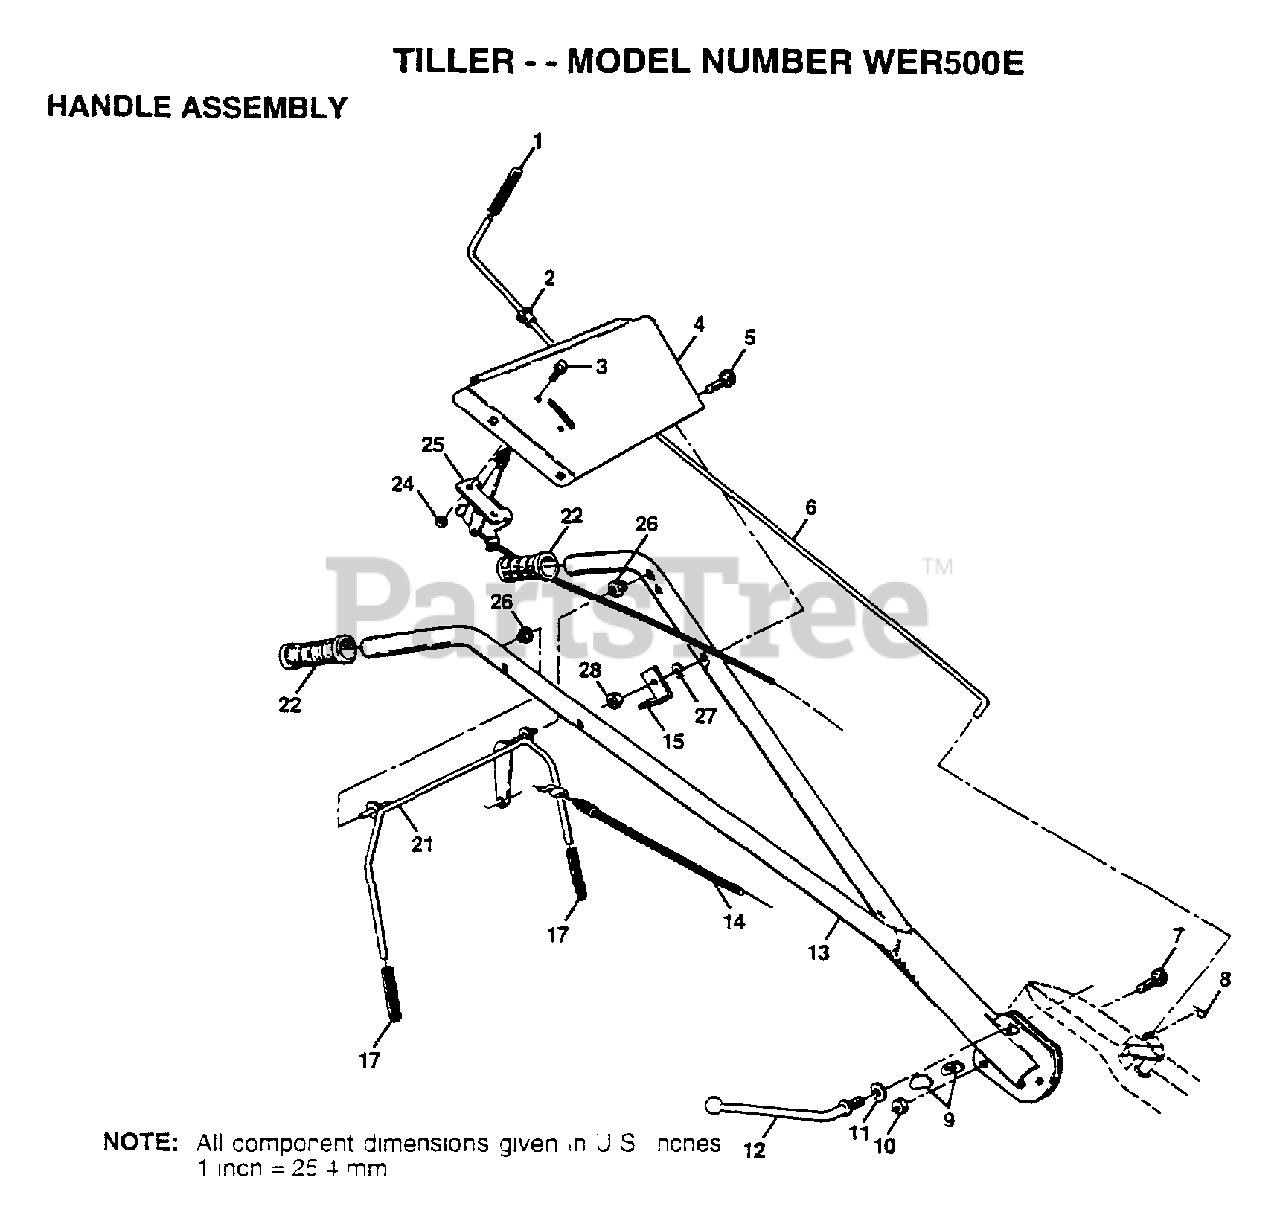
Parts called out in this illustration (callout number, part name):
1	GRIP TI
2	BUSHING
3	SCREW.PNHD.10-24
4	BRACKET.HDLE.TILL
5	BOLT CARRIAGE CRT
6	ROD SHIFT CRT
7	BOLT D
8	RETAINER M
9	LOCK CRT
10	LOCKNUT
11	WASHER CRT
12	LEVER LOCK CRT
13	HANDLE.ASM.V-PLOW
14	CABLE.CLUTCH.Z-BE
15	BRACKET.CLUTCH.CA
17	GRIP BAR CRT
21	BAR.ASM.CNTRL.VPL
22	GRIP HDLE NUBBED
23	NUT
25	"CONT,THROTTLE"
26	GROMMET.HANDLE.V-
27	LOCKWASHER
